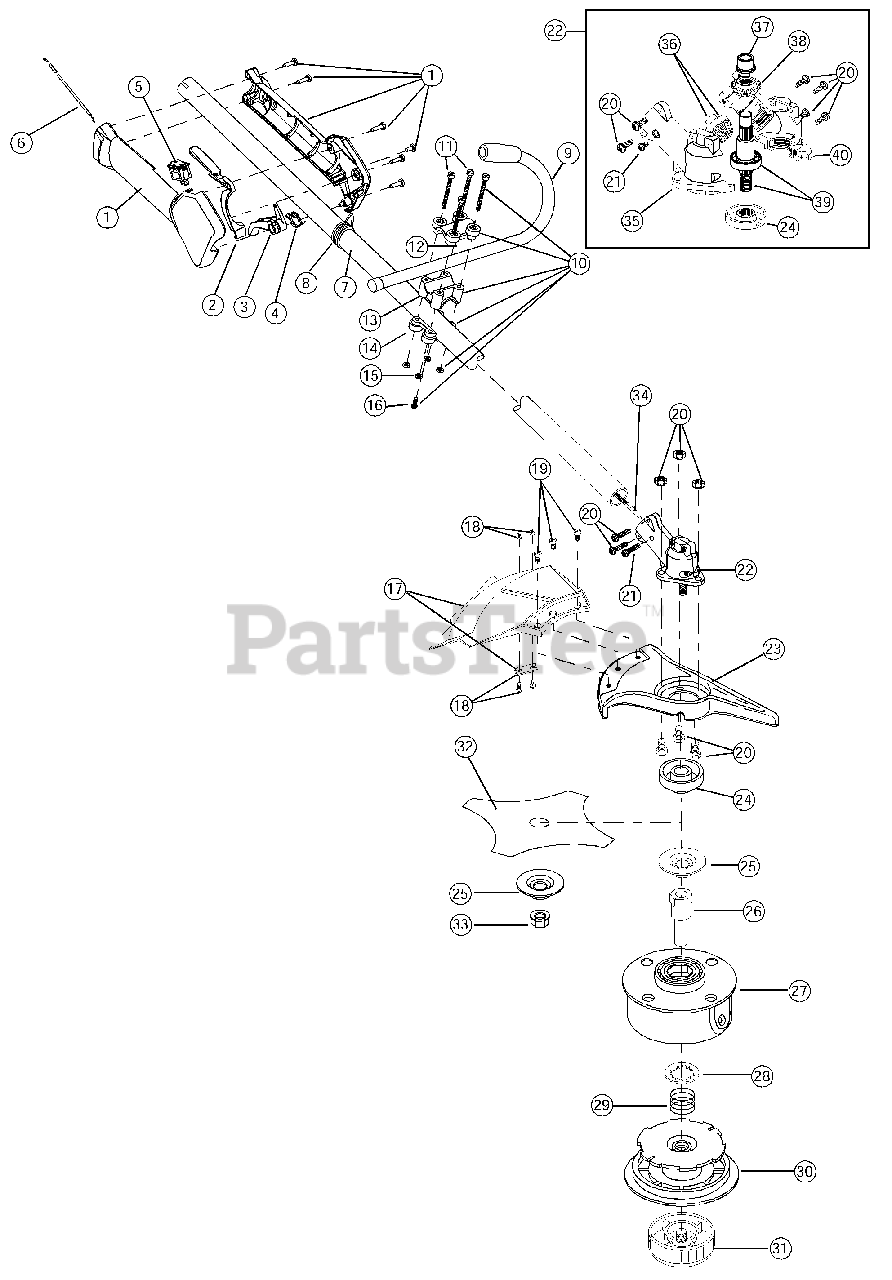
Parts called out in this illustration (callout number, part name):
1	Throttle Housing and Trigger Assembly
2	Throttle Trigger Lock-Out
3	Throttle Trigger
4	Throttle Trigger Spring
5	Switch Assembly
6	Throttle Cable Assembly
7	Upper Drive Shaft Housing Assembly
8	Harness Clip
9	J-Handle Assembly
10	Handle Bracket Assembly
12	Upper Handle Clamp
13	Middle Handle Clamp
14	Lower Handle Clamp
16	Anti-Rotation Screw
17	Shield and Blade Assembly
18	Blade Assembly
19	Shield Mount Screw Assembly
20	Gearbox Mounting Hardware
21	Anti-Rotation Screw
22	Gearbox Assembly
23	Blade Shield
24	Blade Driver
25	Retaining Washer
26	Spool Shaft
27	Outer Spool and Eyelet Assembly
28	Retainer
29	Spring
30	Inner Reel
31	Bump Head Knob Assembly
32	4-Tooth Blade
33	Nut
34	Flexible Drive Shaft
35	Right Housing
36	Pinion Gear Assembly
37	Output Shaft Bushing
38	Output Shaft Gear
39	Output Shaft Assembly
40	Left Housing
